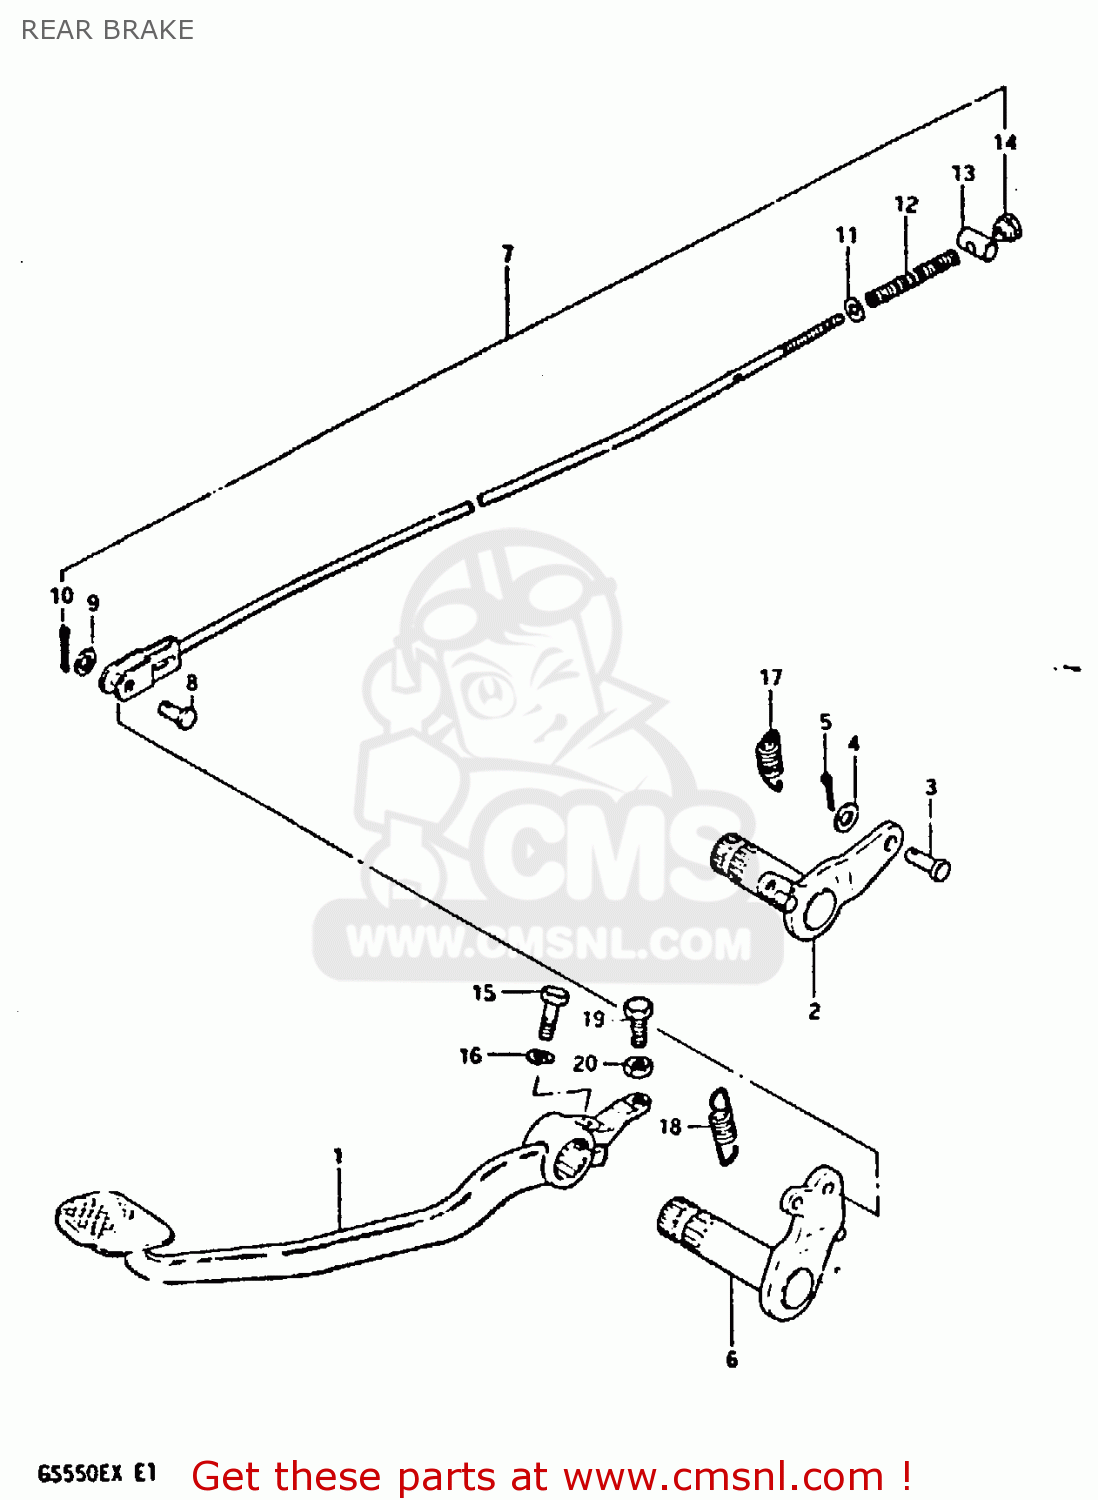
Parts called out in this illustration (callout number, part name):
1	PEDAL,BRAKE
2	ARM,BRAKE PEDAL
3	PIN
4	WASHER
5	PIN
6	ARM,BRAKE PEDAL
7	ROD, REAR BRAKE
8	PIN(L:13.5)
9	WASHER
10	PIN 20X20
11	WASHER
12	SPRING
13	PIN
14	NUT
15	BOLT
16	LOCK WASHER
17	SPRING
18	SPRING
19	BOLT
20	NUT
